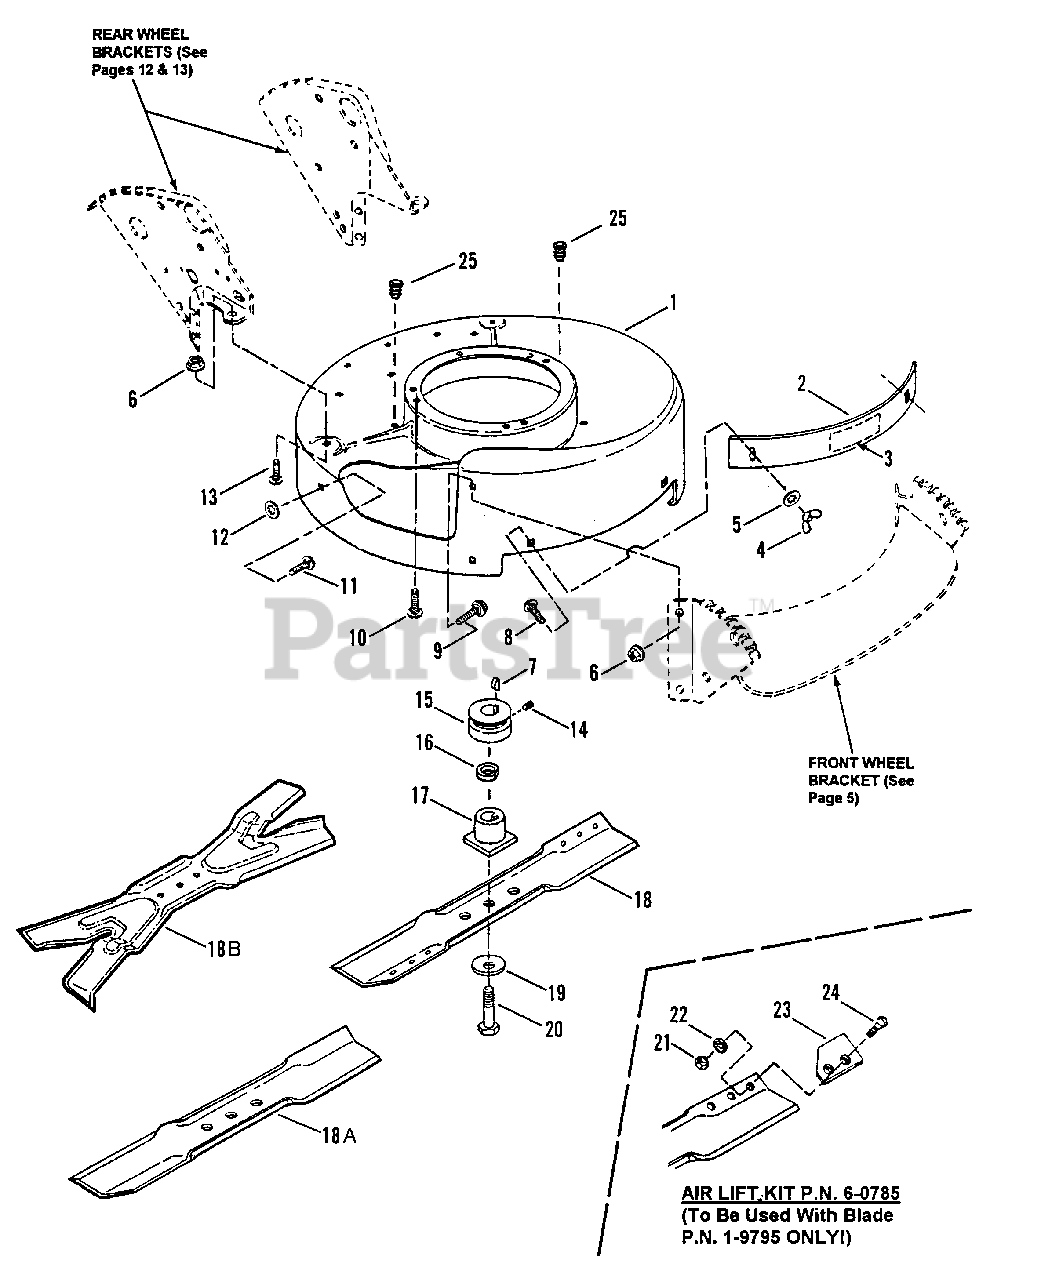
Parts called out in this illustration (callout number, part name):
1	DECK, Mower
2	BAFFLE, Front
3	DECAL, Front Baffle
4	WING-NUT, 5/16-18 Nyloc
5	WASHER, 5/16 Internal/External Tooth Lock
6	NUT, 5/16-18 Hex Flange Lock, Grade 5
7	KEY, Hi-Pro
8	BOLT, 5/16-18 x 1-3/4" Carriage, Grade 5
9	BOLT, 5/16-18 x 1-1/8" Short Neck Carriage, Grade 5
10	SCREW, 3/8-16 x 1" Self-Tapping (Engine Mounting)
11	BOLT, 5/16-18 x 3/4" Short Neck Carriage, Grade 5
12	RETAINER, 5/16 Bolt
13	BOLT, 5/16-18 x 1/2" Short Neck Carriage, Grade 5
14	SCREW, 5/16-18 x 5/16" Hex Socket Set
15	PULLEY, Engine (25mm I.D. x 2-1/8" O.D.)
16	SPACER, Blade Hub
17	HUB, Blade Drive
18	BLADE, Cutter
18A	BLADE, Cutter (Mulching)
18B	BLADE, Cutter (Quad Edge - Ninja)
19	WASHER, Cone
20	SCREW, 3/8-24 x 2 Hex Head Cap, Grade 5
21	NUT, 5/16-24 Hex, Grade 5
22	WASHER, 5/16 Internal Tooth Lock
23	LIFT, Air
24	SCREW, 5/16-24 x 21/32" Machine
25	PLUG, Hole
26	AIR LIFT KIT
